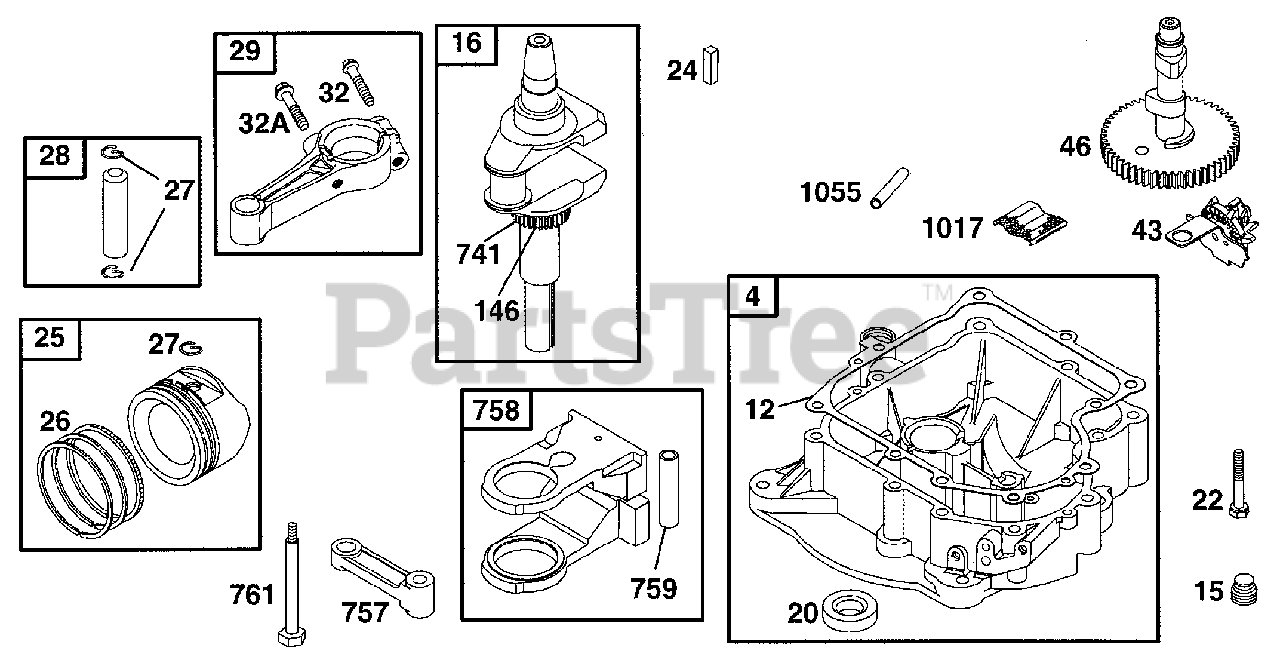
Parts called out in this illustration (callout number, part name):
4	Engine Sump
12	Crankcase Gasket
15	Oil Drain Plug
16	Crankshaft
20	Oil Seal
24	Flywheel Key
25	Piston Assembly
26	Ring Set
27	Piston Pin Lock
28	Piston Pin
29	Connecting Rod
32	Connecting Rod Screw (1-7/8")
32A	Connecting Rod Screw (1-5/8")
43	Governor/Oil Slinger
146	Timing Key
741	Timing Gear
757	Counterweight Link
758	Counterweight
759	Counterweight Pin
761	Hex Screw
1017	Oil Pump Screen
1055	Oil Pump Tube
